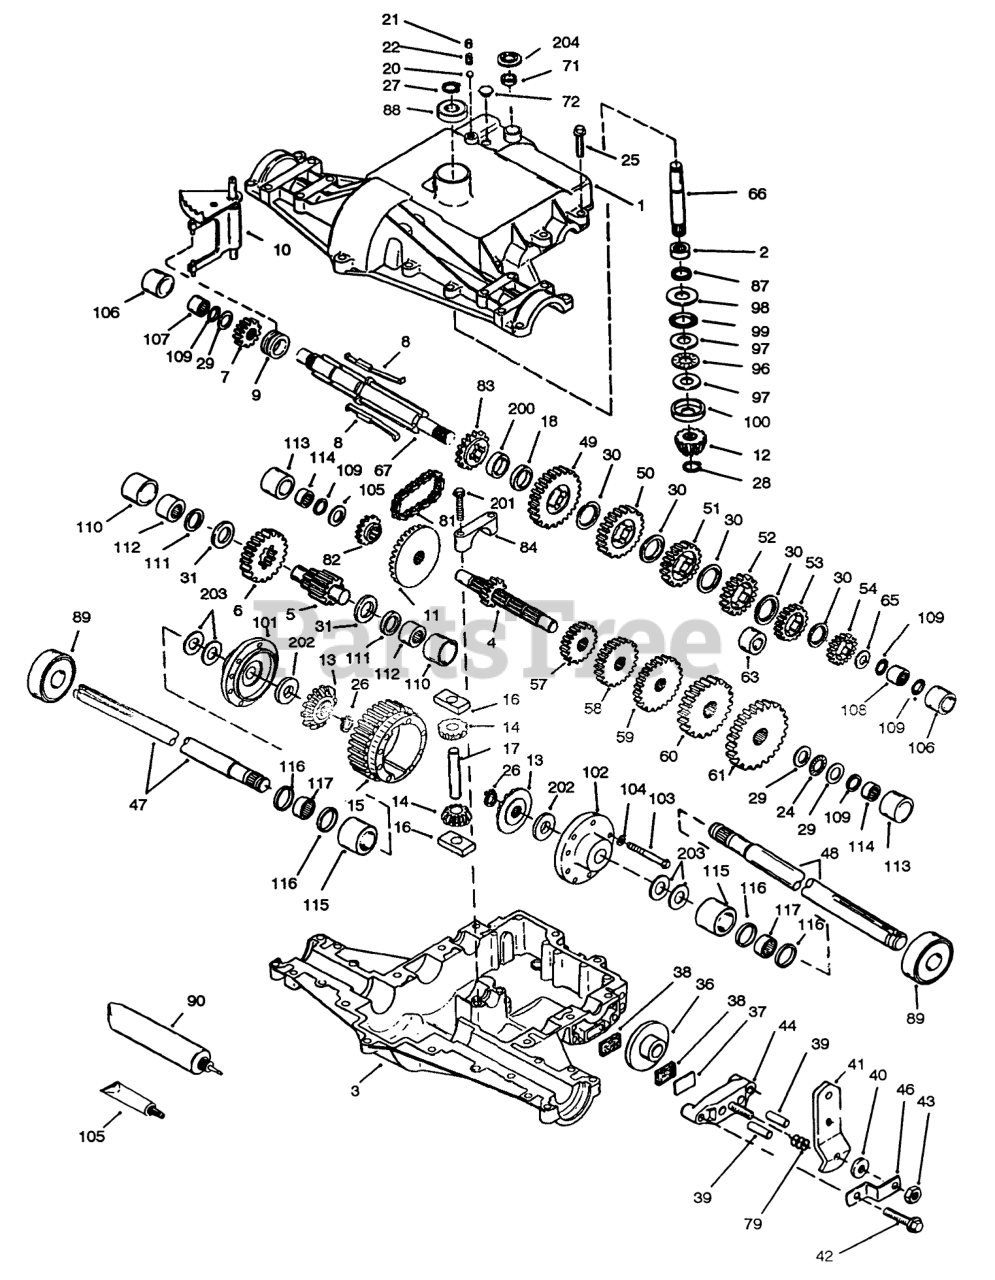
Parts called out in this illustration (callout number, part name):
1	Cover-Transaxle (Only On: 72042, 72062)
2	Bearing-Needle (Only On: 72042, 72062)
3	Case-Transaxle (Only On: 72042, 72062)
4	Countershaft-Gear 9t (Only On: 72042, 72062)
5	Shaft-Output (Only On: 72042, 72062)
6	Gear-Output 35t (Only On: 72042, 72062)
7	Gear-Spur 15t (Only On: 72042, 72062)
8	Key-Shift (Only On: 72042, 72062)
9	Collar-Shift (Only On: 72042, 72062)
10	Fork-Shift (Only On: 72042, 72062)
11	Gear-Bevel 33t (Only On: 72042, 72062)
12	Pinion-Input Bevel 13t (Only On: 72042, 72062)
13	Gear-Bevel 16t (Only On: 72042, 72062)
14	Pinion-Bevel 10t (Only On: 72042, 72062)
15	Gear-Ring (Only On: 72042, 72062)
16	Block-Drive (Only On: 72042, 72062)
17	Pin-Drive (Only On: 72042, 72062)
18	Spacer .350-.340 Thick (Only On: 72042, 72062)
20	Ball-Steel (Only On: 72042,72062)
21	Screw-Set 3/8-16x3/8 (Only On: 72042, 72062)
22	Spring (Only On: 72042, 72062)
24	Bearing-Thrust (Only On: 72042, 72062)
25	Screw 5/16-18x1 1/4 (Only On: 72042, 72062)
26	Ring-Retaining (Only On: 72042, 72062)
27	Ring-Retaining (Only On: 72042, 72062)
28	Ring-Retaining (Only On: 72042, 72062)
29	Washer (Only On: 72042, 72062)
30	Washer (Only On: 72042, 72062)
31	Washer (Only On: 72042, 72062)
36	Washer (Only On: 72042, 72062)
37	Plate-Brake Pad (Only On: 72042, 72062)
38	Pad-Brake 2/Pkg (Only On: 72042, 72062)
39	Pin-Dowel (Only On: 72042, 72062)
40	Washer (Only On: 72042, 72062)
41	Lever-Brake (Only On: 72042, 72062)
42	Screw 1/4-20x1 1/4 (Only On: 72042, 72062)
43	Nut-Lock 5/16x24 (Only On: 72042, 72062)
44	Holder-Brake Pad (Only On: 72042, 72062)
46	Bracket-Brake Lever (Only On: 72042, 72062)
47	Axle 12 9/16" Long (Only On: 72042, 72062)
48	Axle 16 7/16" Long (Only On: 72042, 72062)
49	Gear-Spur 41t (Only On: 72042, 72062)
50	Gear-Spur 35t (Only On: 72042, 72062)
51	Gear-Spur 30t (Only On: 72042, 72062)
52	Gear Spur 25t (Only On: 72042,72062)
53	Gear Spur 22t (Only On: 72042, 72062)
54	Gear Spur 19t (Only On: 72042, 72062)
57	Gear Spur 15t (Only On: 72042, 72062)
58	Gear Spur 20t (Only On: 72042, 72062)
59	Gear Spur 25t (Only On: 72042, 72062)
60	Gear Spur 28t (Only On: 72042, 72062)
61	Gear Spur 30t (Only On: 72042, 72062)
65	Washer (Only On: 72042, 72062)
66	Shaft-Input 30.910" Lg (Only On: 72042, 72062)
67	Shaft-Shifter/Brake (Only On: 72042, 72062)
71	Ring-Square Cut (Only On: 72042, 72062)
72	Plug-Threaded 9/16-18 (Only On: 72042, 72062)
79	Spring (Only On: 72042, 72062)
81	Chain-Roller #41 22" Lg (Only On: 72042, 72062)
82	Sprocket 10t (Only On: 72042, 72062)
83	Sprocket-Reverse 14t (Only On: 72042, 72062)
84	Cap-Bearing (Only On: 72042, 72062)
87	Seal-Oil 3/4" (Only On: 72042, 72062)
88	Bearing-Ball (Only On: 72042, 72062)
89	Bearing-Ball (Only On: 72042, 72062)
90	Grease 32 Oz Bentonite (Only On: 72042, 72062)
96	Bearing-Thrust (Only On: 72042, 72062)
97	Washer (Only On: 72042, 72062)
98	Washer (Only On: 72042, 72062)
99	O-Ring (Only On: 72042, 72062)
100	Washer-Cupped (Only On: 72042, 72062)
101	Carrier-Differential (Only On: 72042, 72062)
102	Carrier-Differential (Only On: 72042, 72062)
103	Screw 14-20x2 1/4 (Only On: 72042, 72062)
104	Washer-Lock (Only On: 72042, 72062)
105	Washer (Only On: 72042, 72062)
106	Sleeve (Only On: 72042, 72062)
107	Bearing-Needle (Only On: 72042, 72062)
108	Bearing-Needle (Only On: 72042, 72062)
109	O-Ring (Only On: 72042, 72062)
110	Sleeve (Only On: 72042, 72062)
111	Ring-Square Cut (Only On: 72042, 72062)
112	Bearing-Needle (Only On: 72042, 72062)
113	Sleeve (Only On: 72042, 72062)
114	Bearing-Needle (Only On: 72042, 72062)
115	Sleeve (Only On: 72042, 72062)
116	Ring-Square Cut (Only On: 72042, 72062)
117	Bearing-Needle (Only On: 72042, 72062)
150	Gasket Loctite #515 (Only On: 72042, 72062)
200	Spacer .276-.268 Thick (Only On: 72042, 72062)
201	Screw 1/4-20x1 1/4 (Only On: 72042, 72062)
202	Washer (Only On: 72042, 72062)
203	Washer (Only On: 72042, 72062)
204	Nut-Push (Only On: 72042, 72062)
